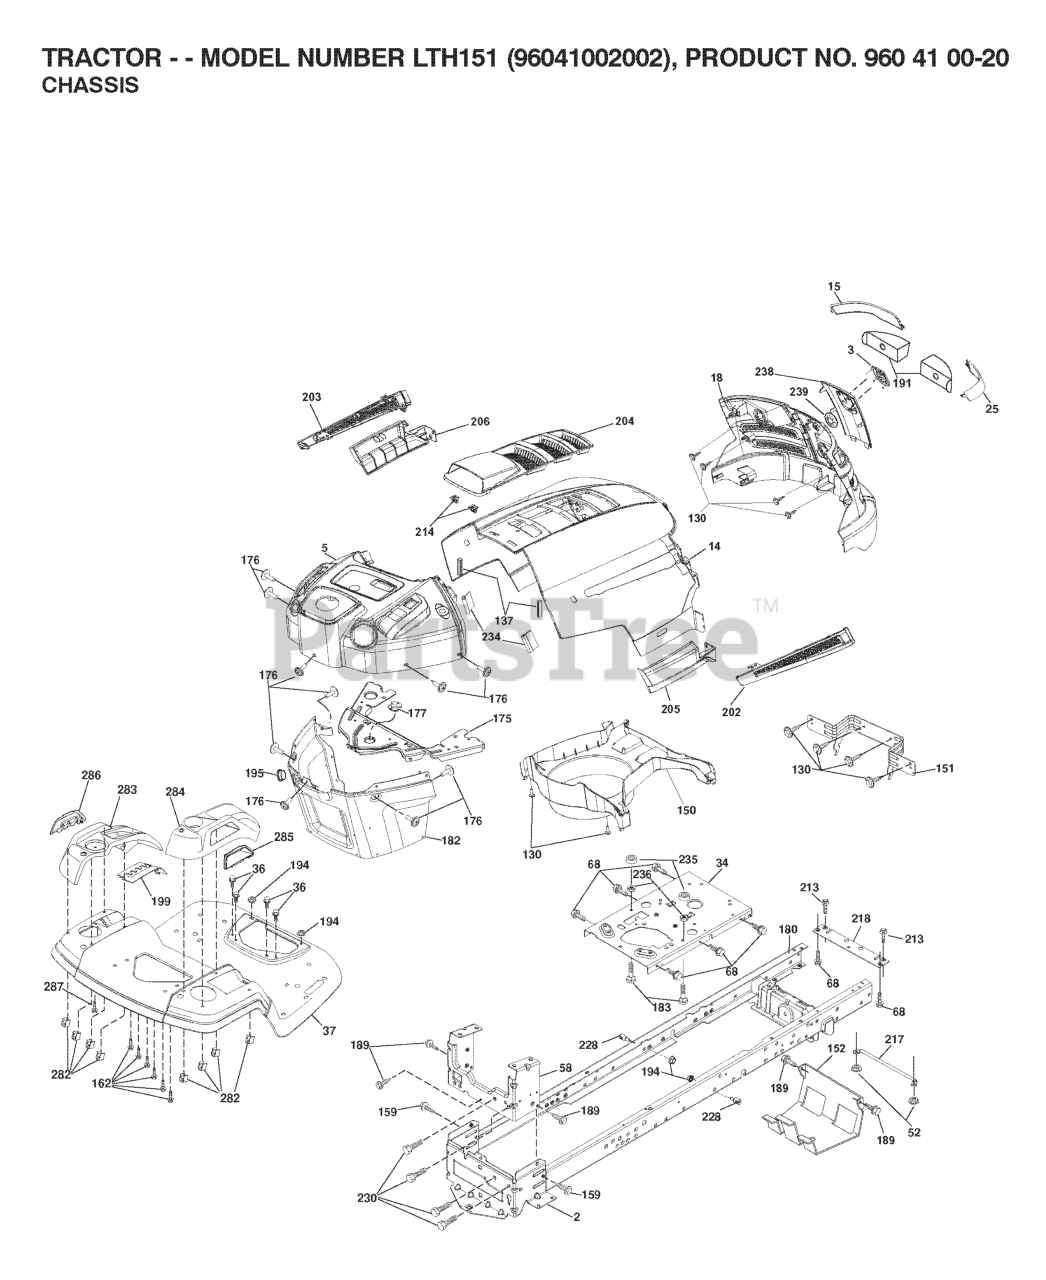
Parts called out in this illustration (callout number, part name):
2	DRAWBAR.LOWER.2PC.18/22
3	RP LOGO
5	DASH
14	HOOD
15	LENS.HUSQVARNA LT.LH
18	RP GRILLE/LENS ASM.
25	LENS.HUSQVARNA LT.RH
34	PLATE.ENGINE.WELDED.CHASSIS
36	SCREW 5/16"
37	RP FENDER.TLT.FS.W/CPH.422
52	LOCKNUT
58	DRAWBAR UPPER 2PC SMALL FENDER
68	Screw 5/16-18 x 1/2 Hex, Self Tapping 5/16-18 x 1/2
130	SCREW
137	BUMPER DASH
151	BRACKET PIVOT
152	SHIELD.BROWNING.W/TEX
159	SCREW, 3/8-16X3/4
162	SCREW.HI-LO.CONSOLE
175	CROSSMEMBER
176	SCREW.#10-24X5/8.RN.QU
177	BUSHING STEERING
180	CHASS.WLDMNT.TL.12GA/2P.48/54
182	DASH.LOWER.PREDATOR LT
183	BOLT.5/16-18X1-1/4 FULL.THREAD
189	SCREW
191	INSERT REFLECTIVE
194	NUT LOCK HEX FLANGE 5/16-18
195	PLUG DASH
199	PLATE.DECK.LIFT.HUSQ.LT
202	VENT SIDE HOOD RH
203	VENT SIDE HOOD LH
204	VENT TOP HOOD
205	SKIRT SIDE RH
206	SKIRT SIDE LH
213	BOLT
214	CLIP.RETAINER.TINNER.
217	ROD.PIVOT.HOOD
218	X-PIECE.HOOD.STOP.NON/
228	STUD.FASTNER.W/ANTI-ROTATE
230	SHOULDER BOLT 5/16-18TT
234	BUMPER.HOOD.TEX.HUSQVARNA
235	SPACER FENDER
236	NUT.CENTERLOCK.5/16-
238	TRIM
282	CLIP.RETAINER.CONSOLE.LT.HUSQ
283	CONSOLE.DECK.LIFT.HUSQ.N/FR.GR
284	CONSOLE.SHFT.HYD,HUSQL
285	CONSOLE INSERT RH
286	CONSOLE.INSRT.LH.HUSQ.LT.BLACK
287	SCREW 1/4X20
